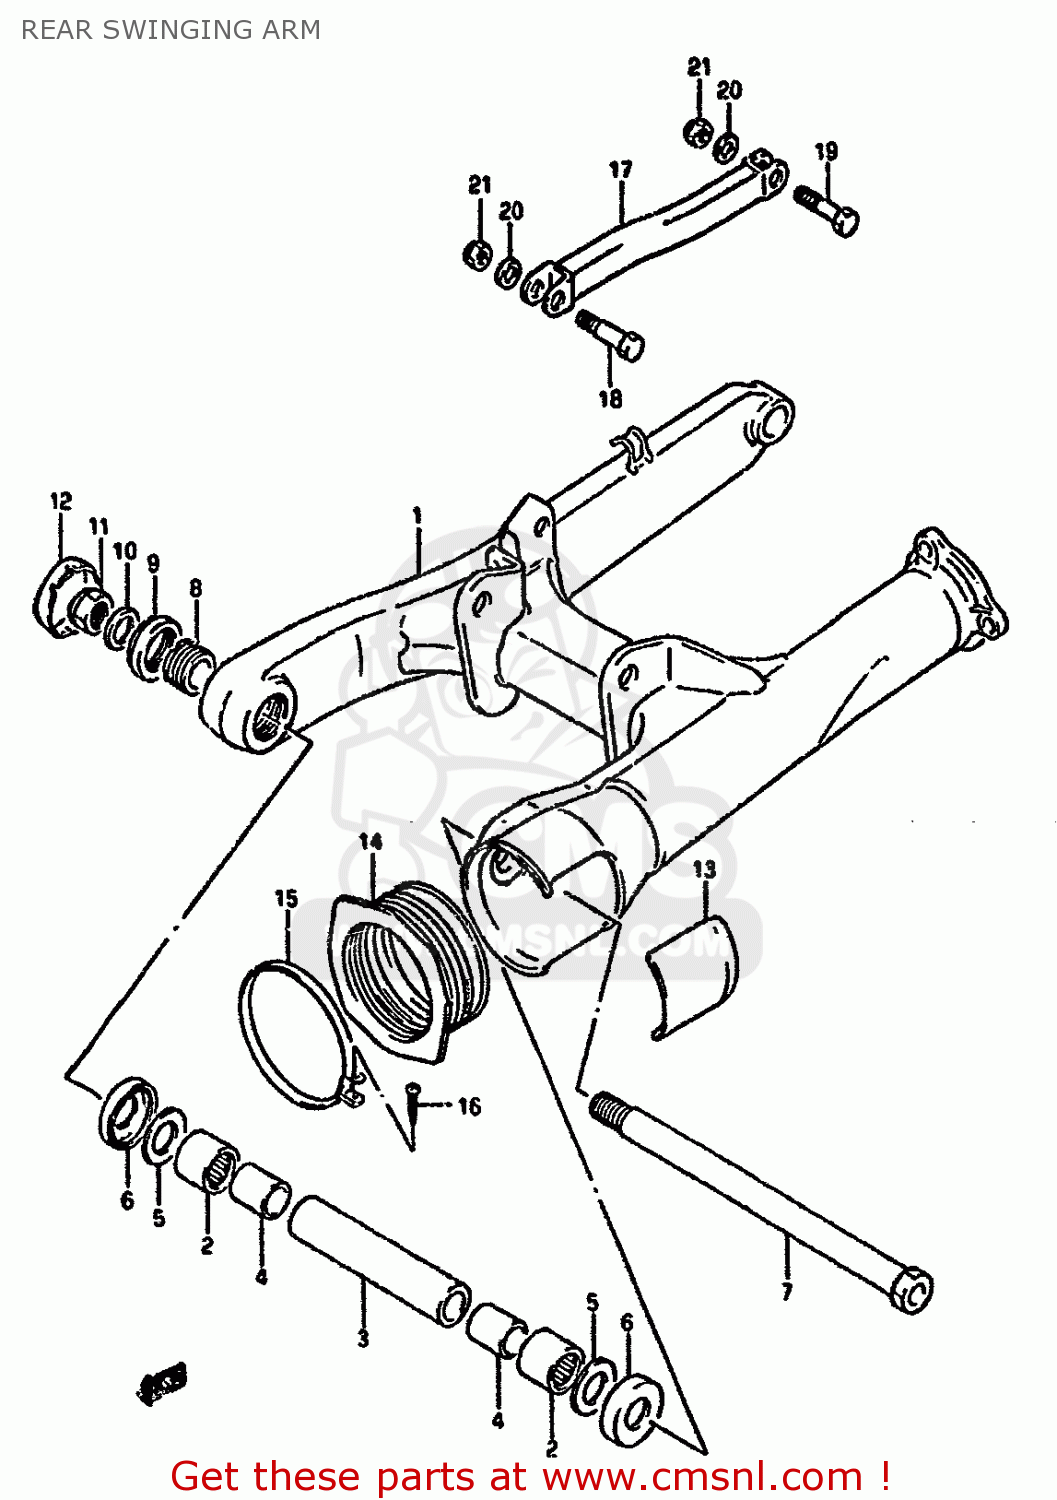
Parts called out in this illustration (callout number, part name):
1	SWING ARM ASSEMBLY,REAR
2	BEARING(25X33X30)
3	SPACER (20.8X27.2X143)
4	SPACER,RR SWGARM PIVOT BERRING
5	WASHER
6	COVER,RR SWGARM PIVOT SEAL
7	SHAFT,REAR SWING ARM
8	BOLT,RR SWGARM PIVOT
9	NUT,REAR SWING ARM PIVOT
10	WASHER (18.2X28X2.6)
11	NUT
12	CAP,SWINGINGARM PIVOT
13	COVER,REAR SWING ARM PIVOT
14	BOOT,PROPELLER SHAFT
15	CLAMP
16	SCREW
17	TORQUELINK,RR
18	BOLT,FRONT
19	BOLT(10X34)
20	WASHER
21	NUT
